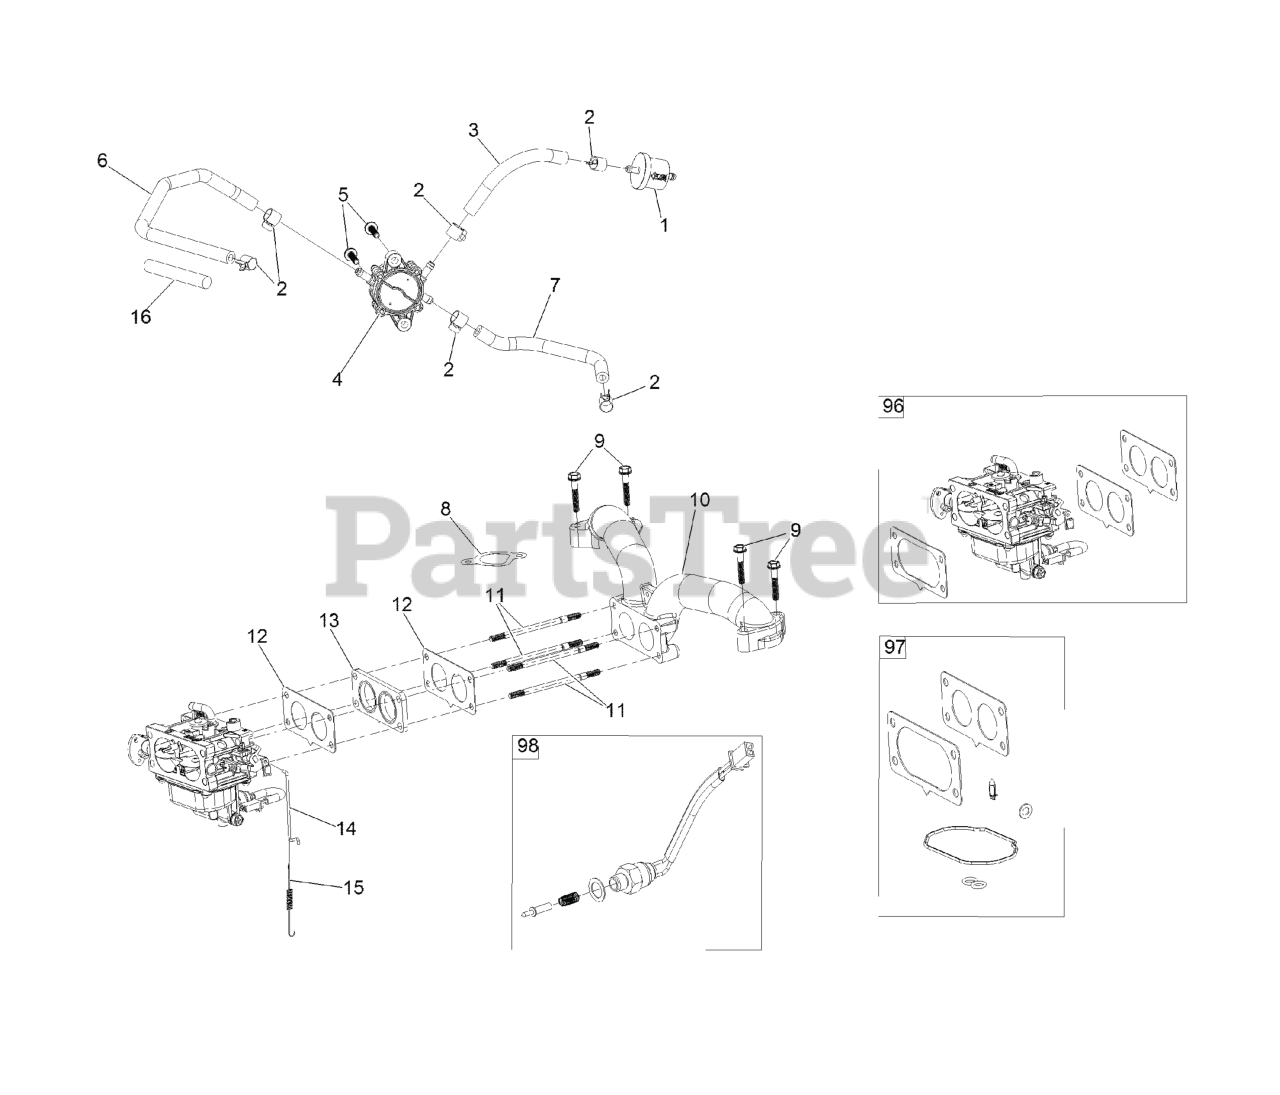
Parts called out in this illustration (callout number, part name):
1	FILTER-FUEL
2	CLAMP-FUEL LINE
3	LINE-FUEL
4	PUMP-FUEL
5	SCREW-HHF
6	HOSE-FUEL
7	HOSE-FUEL
8	GASKET-INTAKE
9	SCREW-HHF
10	MANIFOLD-INTAKE
12	GASKET-CARBURETOR
13	INSULATOR-CARBURETOR
14	LINKAGE-THROTTLE
15	SPRING-RETURN, THROTTLE
16	SLEEVE-FUEL LINE PROTECTO
96	CARBURETOR REPLACEMENT KI
97	CARBURETOR REPAIR KIT
98	SOLENOID KIT
